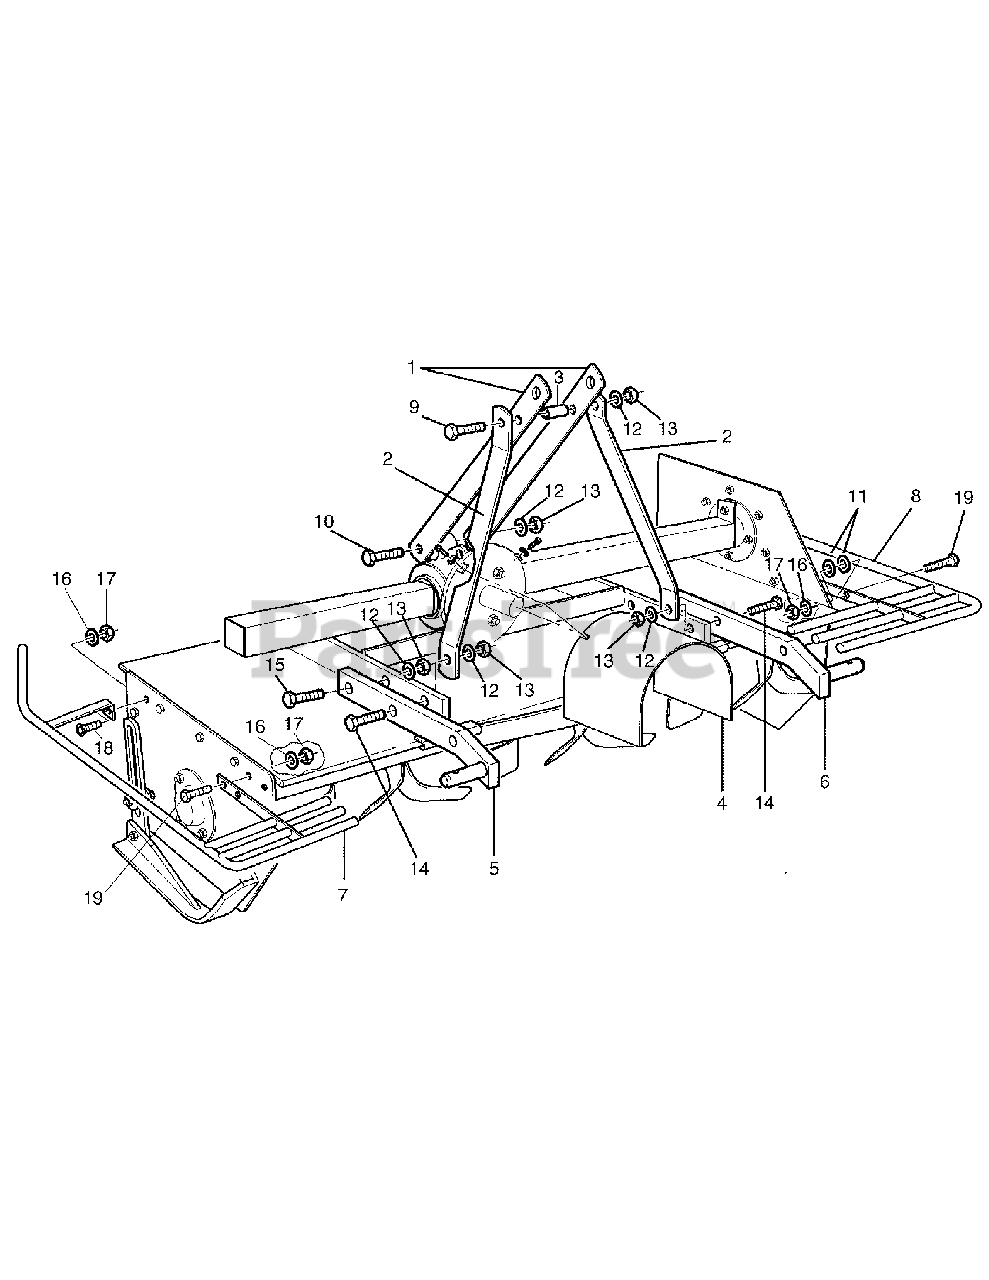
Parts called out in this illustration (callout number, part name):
1	Top hitch arm
2	Top hitch support
3	Spacer
4	Pto shaft protection
5	Lower right hitch plate
6	Left lower hitch plate
7	Complete right protection
8	Complete left protection
9	Bolt TE M12x100
10	Bolt TE M12x90
11	Flat washer Ø10
12	Washer Ø12
13	Nut M12
14	Bolt TE M12x60
15	Bolt TE M12x50
16	Washer Ø10
17	Nut M10
18	Flat head bolt TSPEI M10x35
19	Bolt TE M10x35
